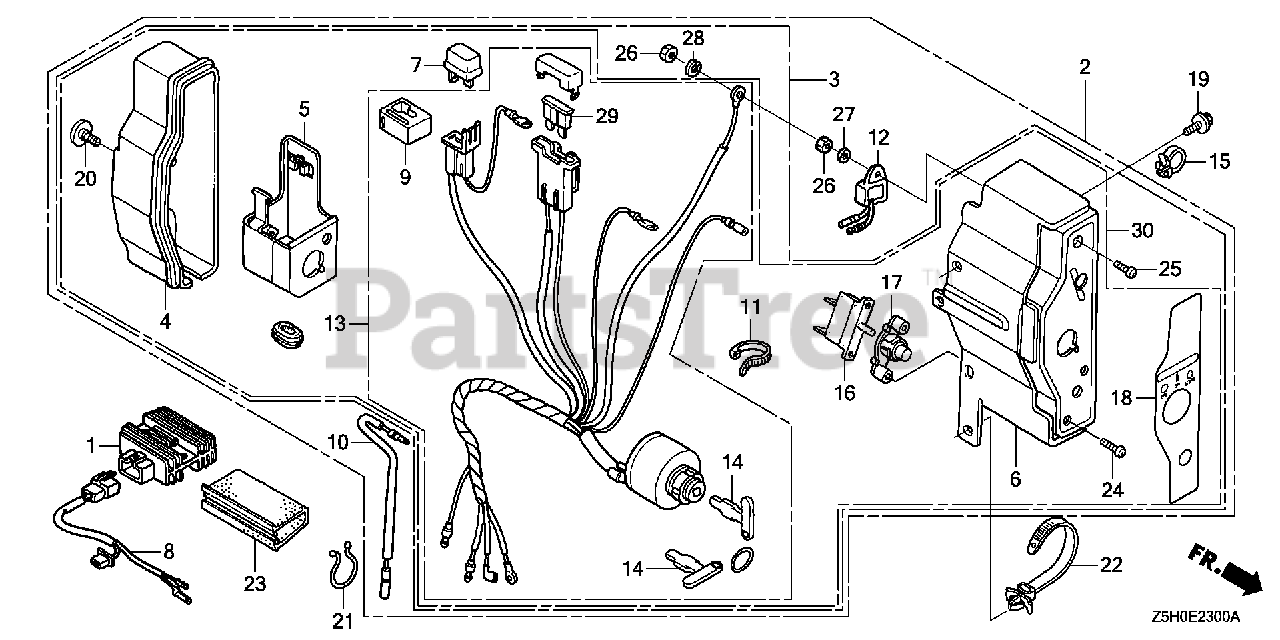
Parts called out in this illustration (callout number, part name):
2	BOX ASSY., CONTROL (3A) *R280* (EXP-ALERT) (POWER RED)
4	CASE, CONTROL
5	BRACKET, CASE MOUNTING
6	PANEL, CONTROL *R280* (POWER RED)
7	RECTIFIER ASSY., SILICON (SHINDENGEN)
9	SUSPENSION, CONNECTOR
10	SUB-WIRE HARNESS
12	ALERT UNIT, OIL
13	SWITCH ASSY., COMBINATION (3A-CHARGE)
14	KEY (HONDALOCK)
15	HOLDER, STOP SWITCH WIRE
16	PROTECTOR, CIRCUIT (3.5A)
17	LENS ASSY., PROTECTOR
18	MARK, CONTROL BOX (EXTERNAL)
19	BOLT, FLANGE (6X12) (CT200)
20	SCREW, SPECIAL (6X12)
21	CLIP, PURSE LOCK
22	STRAP, CABLE (118MM) (BLACK)
23	TUBE, FASTENER (30MM)
24	SCREW, PAN (3X12)
25	SCREW, PAN (4X12)
26	NUT, HEX. (4MM) (SOURCE: VINTAGE PARTS INC.)
27	WASHER, PLAIN (4MM)
28	WASHER, SPRING (4MM)
29	FUSE, BLADE (15A)
